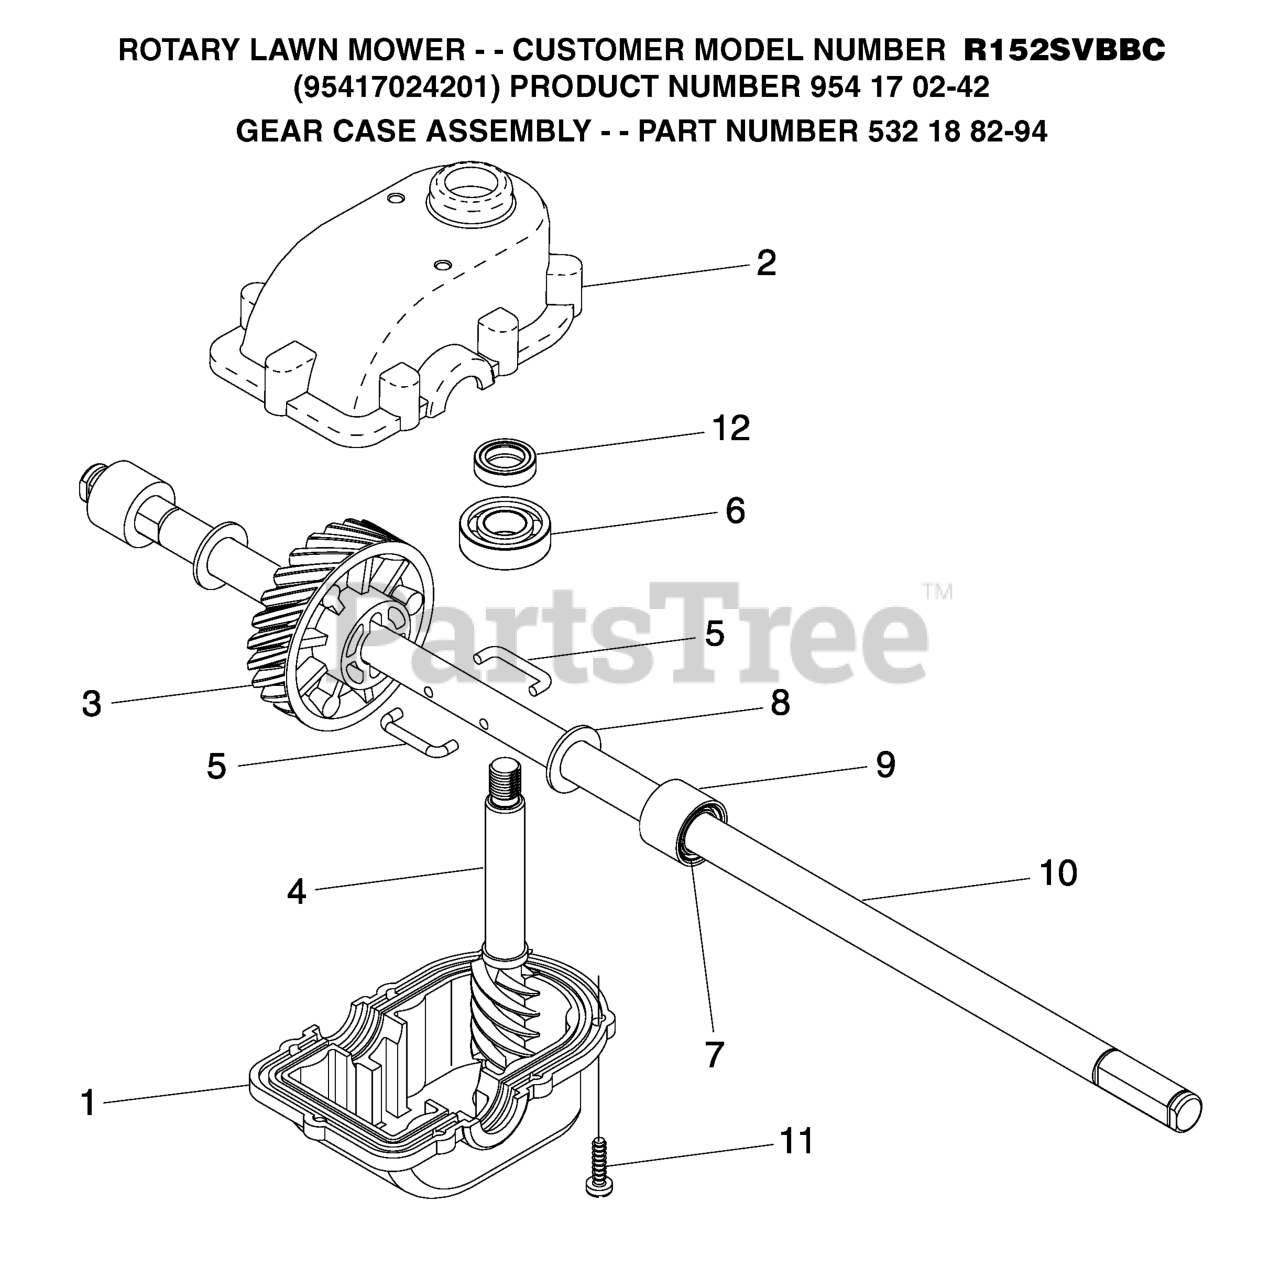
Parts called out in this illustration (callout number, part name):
1	CASE, LOWER
2	GEARCASE.HOUSING
3	GEAR.24.TOOTH.WALK.MOWER
5	WIRE, FORMED (15966)
7	SEAL.OUTPUT.SHAFT
10	SHAFT OUTPUT
12	SEAL INPUT SHAFT
